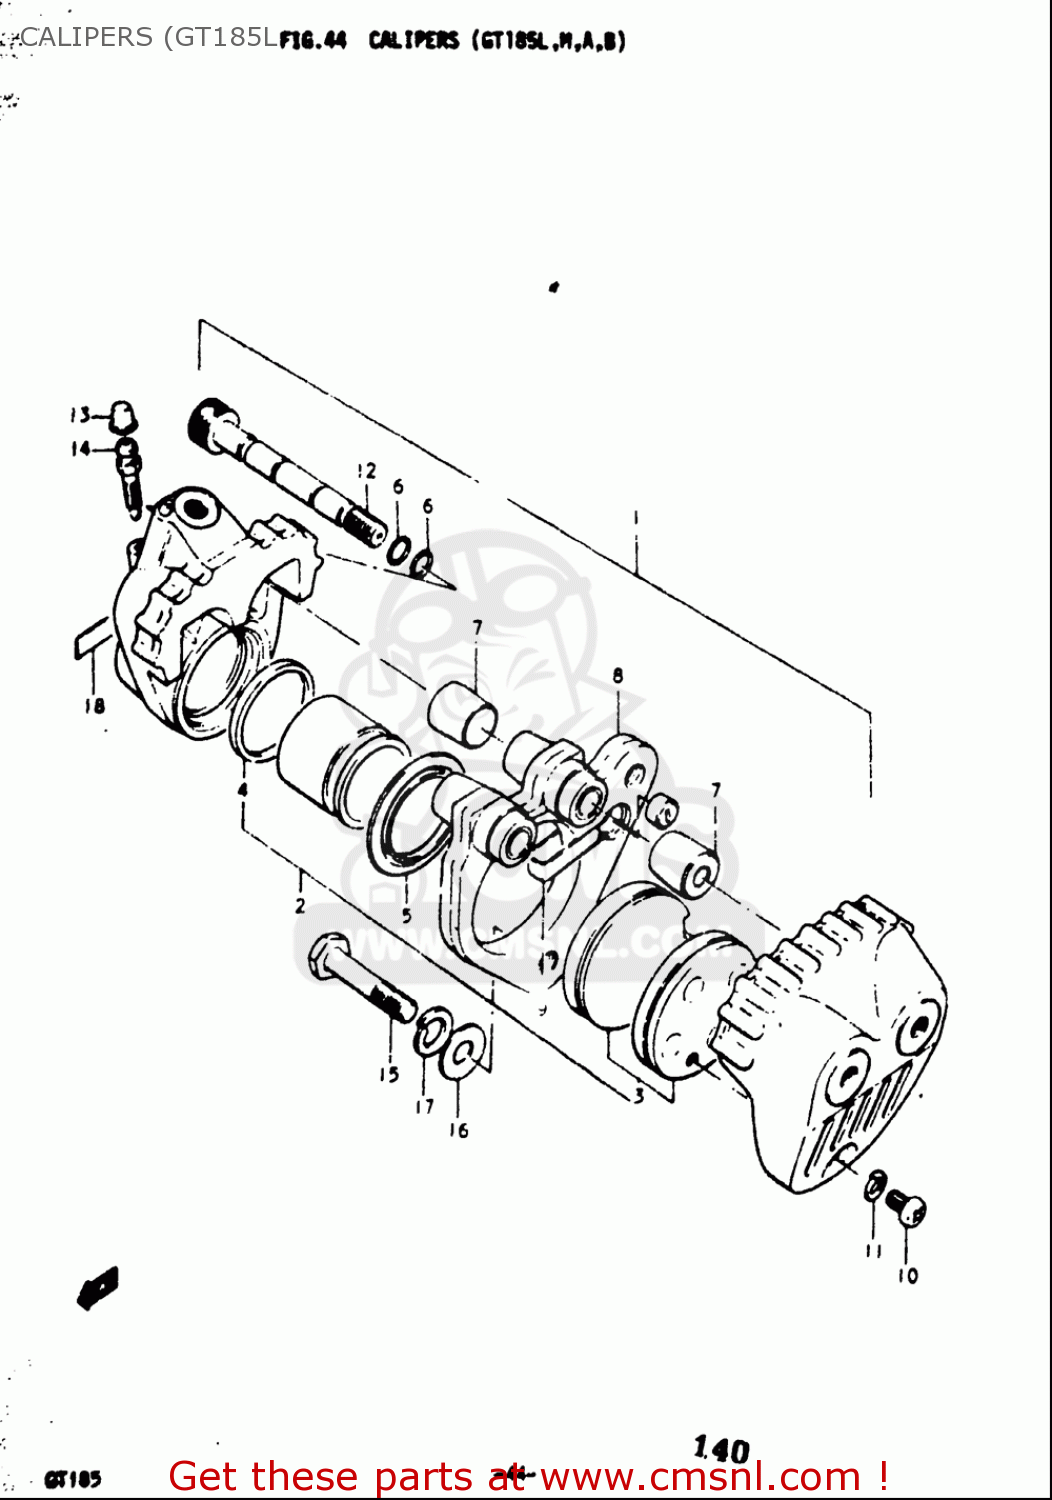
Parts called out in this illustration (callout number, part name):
3	PAD SET
4	SEAL,PISTON
5	BOOT,PISTON
6	O RING,CALIPER AXLE
7	COVER,AXLE DUST
10	SCREW
11	WASHER,LOCK
12	AXLE,CALIPER
13	CAP,BLEEDER PLUG
14	BLEEDER
15	BOLT(10X38)
16	WASHER
17	WASHER,LOCK
